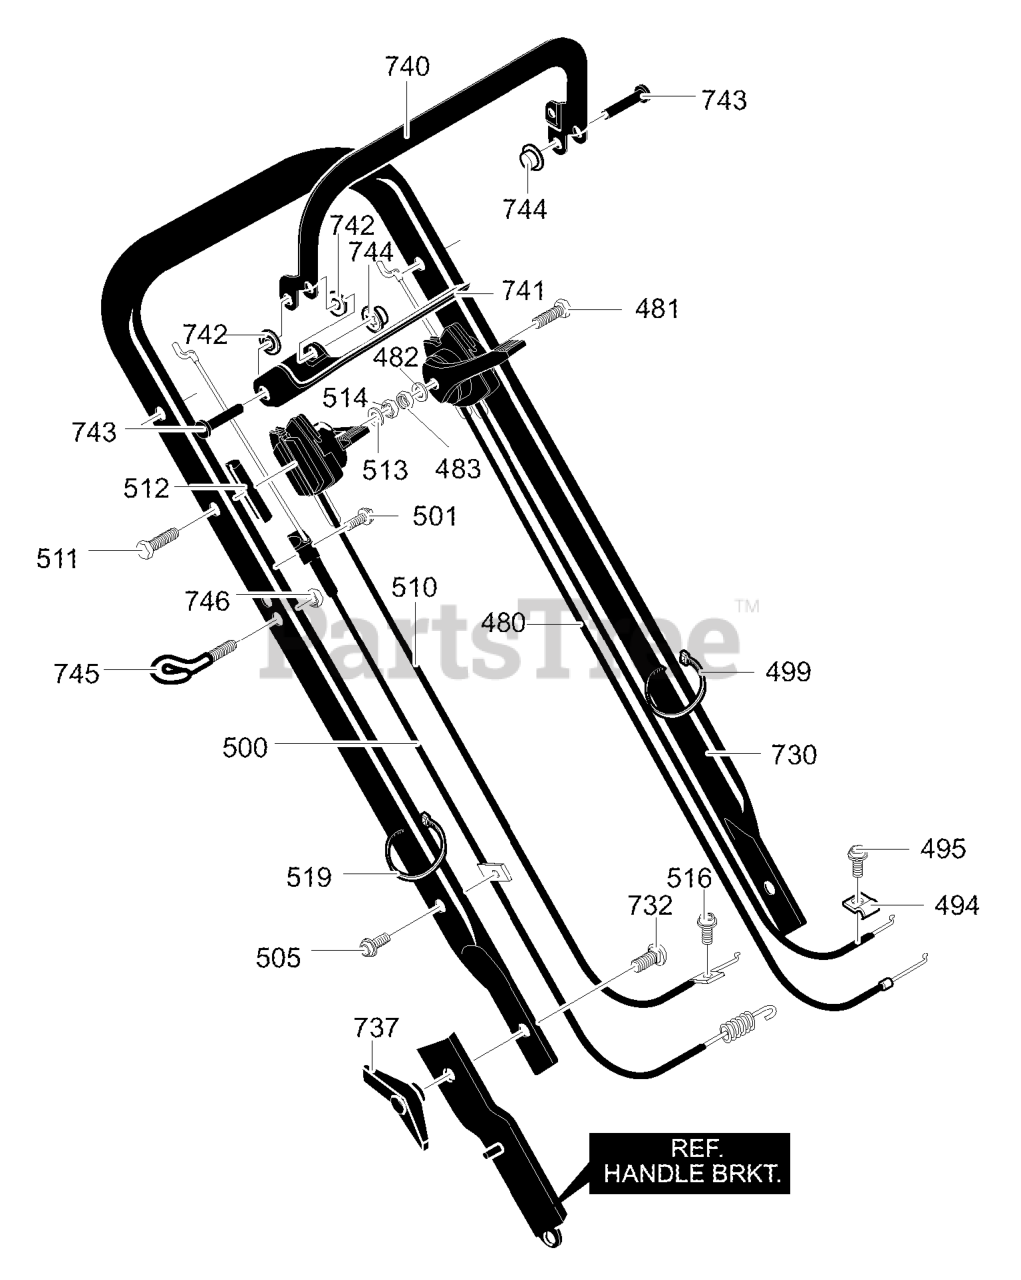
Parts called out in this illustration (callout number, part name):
480	Cable, Restart & Throttle
481	Screw, 1/4-20x2.50
482	Flatwasher
483	Nut, 1/4-20
494	Clamp, Throttle
495	Screw, 10-32x.62
499	Cable Tie
500	Cable, Drive Assy.
501	Screw, #10-16x1.25
505	Screw, 10-16x.50
510	Cable, Shifter Speed
511	Screw, 1/4-20x3.00
512	Spacer, T-Control
513	Flatwasher
514	Nut, 1/4-20
516	Screw, 10-32x.62
519	Cable Tie
732	Bolt, 5/16-18x1.5 Carr.
737	Knob, Wing
740	Lever, Stop
741	Lever, Drive Control
742	Washer, Nylon
743	Pin, Clevis
744	Cap, Push On
745	Rope Guide
746	Nut, 1/4-20
